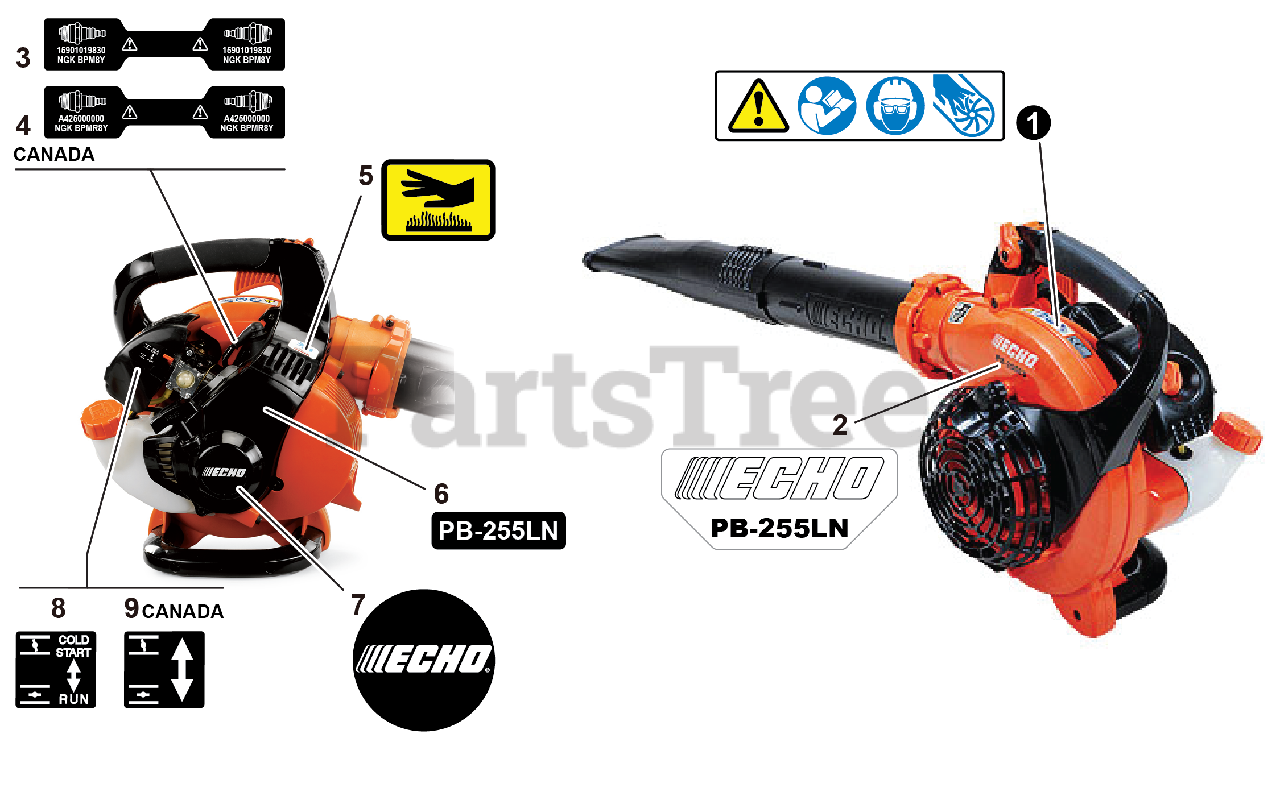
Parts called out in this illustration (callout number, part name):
1	LABEL, CAUTION - ISO
2	LABEL, ECHO PB-255LN
3	LABEL, SPARK PLUG - BPM8Y
4	LABEL, SPARK PLUG - BPMR8Y
5	LABEL, CAUTION - HOT
6	LABEL, MODEL PB-255LN
7	LABEL, ECHO
8	LABEL, CHOKE
9	LABEL, CHOKE
